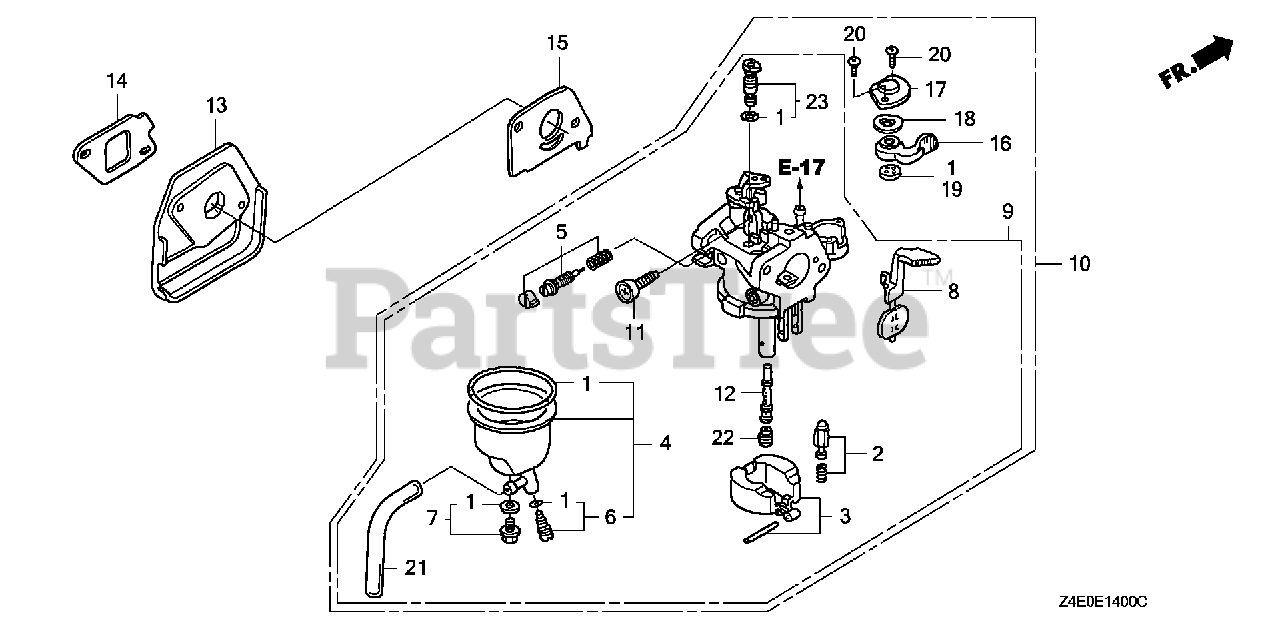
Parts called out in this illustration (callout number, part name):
1	GASKET SET
2	VALVE SET, FLOAT (CARBURETOR NO.) (SEAT NOT INCLUDED)
4	CHAMBER SET, FLOAT (CARBURETOR NO.)
5	SCREW SET (Honda Code 4219879). (CARBURETOR NO.)
6	SCREW SET, DRAIN (CARBURETOR NO.)
7	SCREW SET (CARBURETOR NO.)
8	CHOKE SET (CARBURETOR NO.)
10	CARBURETOR ASSY. (BF32F A)
10	CARBURETOR ASSY. (BF32F C)
10	CARBURETOR ASSY. (BF32H B)
11	SCREW, THROTTLE STOP
12	NOZZLE, MAIN
13	INSULATOR, CARBURETOR
14	GASKET, INSULATOR
15	GASKET, CARBURETOR
16	LEVER, PETCOCK
17	PLATE, LEVER SETTING (CARBURETOR NO.)
18	SPRING, PETCOCK LEVER (CARBURETOR NO.)
19	GASKET, VALVE
20	SCREW, PAN (3X6)
21	BULK HOSE, VINYL (3.5X6.5X8000) (9500(95003-05001-60M) (CARBURETOR NO.)
22	JET, MAIN (#55) Use from Engine SN BF22B D.
22	JET, MAIN (#58) Use from Engine SN BF22B D.
22	JET, MAIN (#60)
23	JET SET, PILOT (#35)
